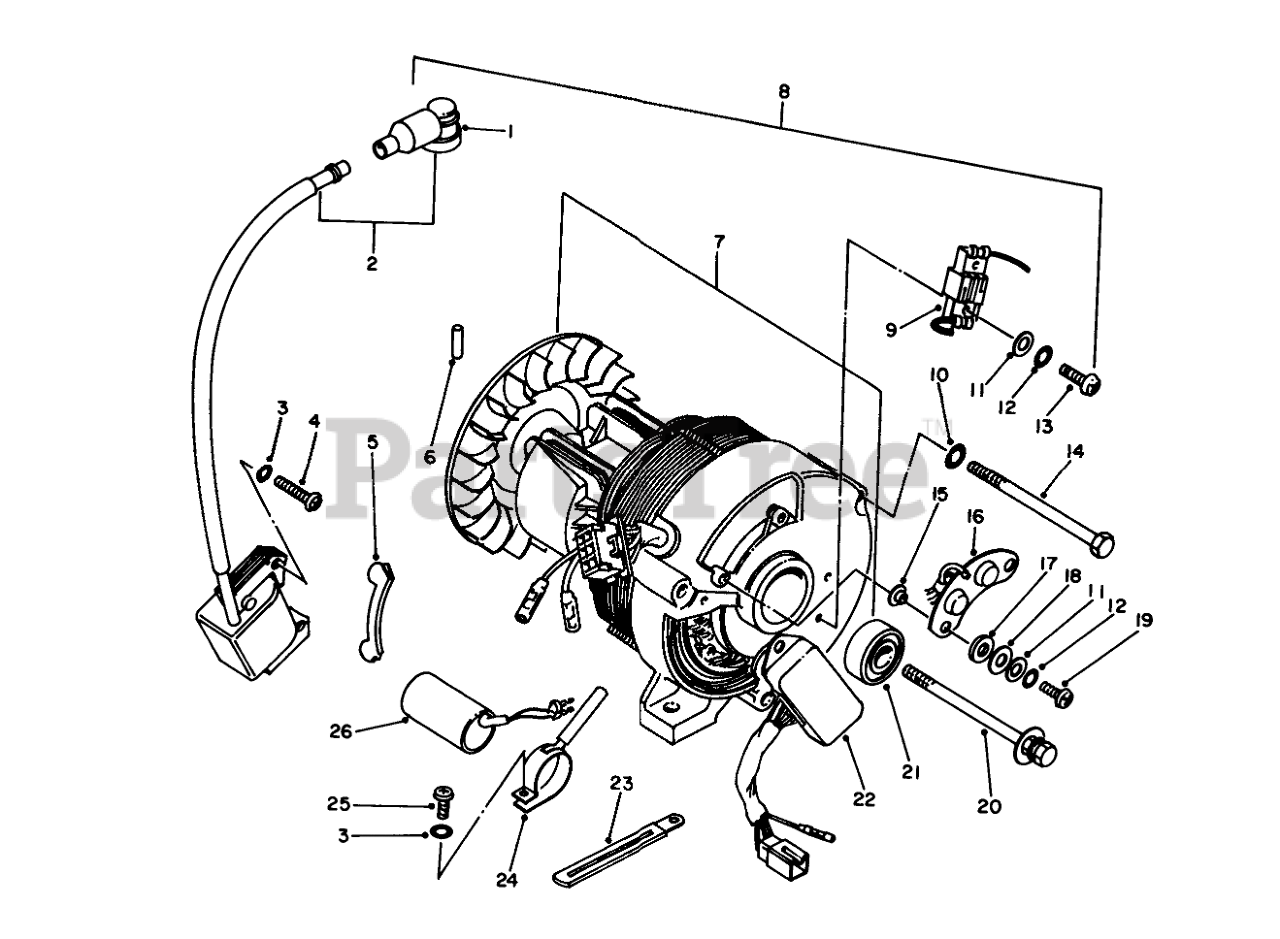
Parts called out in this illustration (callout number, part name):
1	CAP ASM
2	STARTOR ASM
3	Washer
4	Screw
5	Seal-Stator
7	Rotor
8	Generator Assembly
9	Holder Brush
10	Lockwasher
11	Washer
12	Lockwasher
13	Screw
15	Bushing
16	Diode
17	Washer
18	Washer
19	Screw
20	Bolt (L:125)
21	Bearing
22	A.V.R.
23	Clamp
24	Bracket
25	SCREW
26	Capacitor (10 UF)
